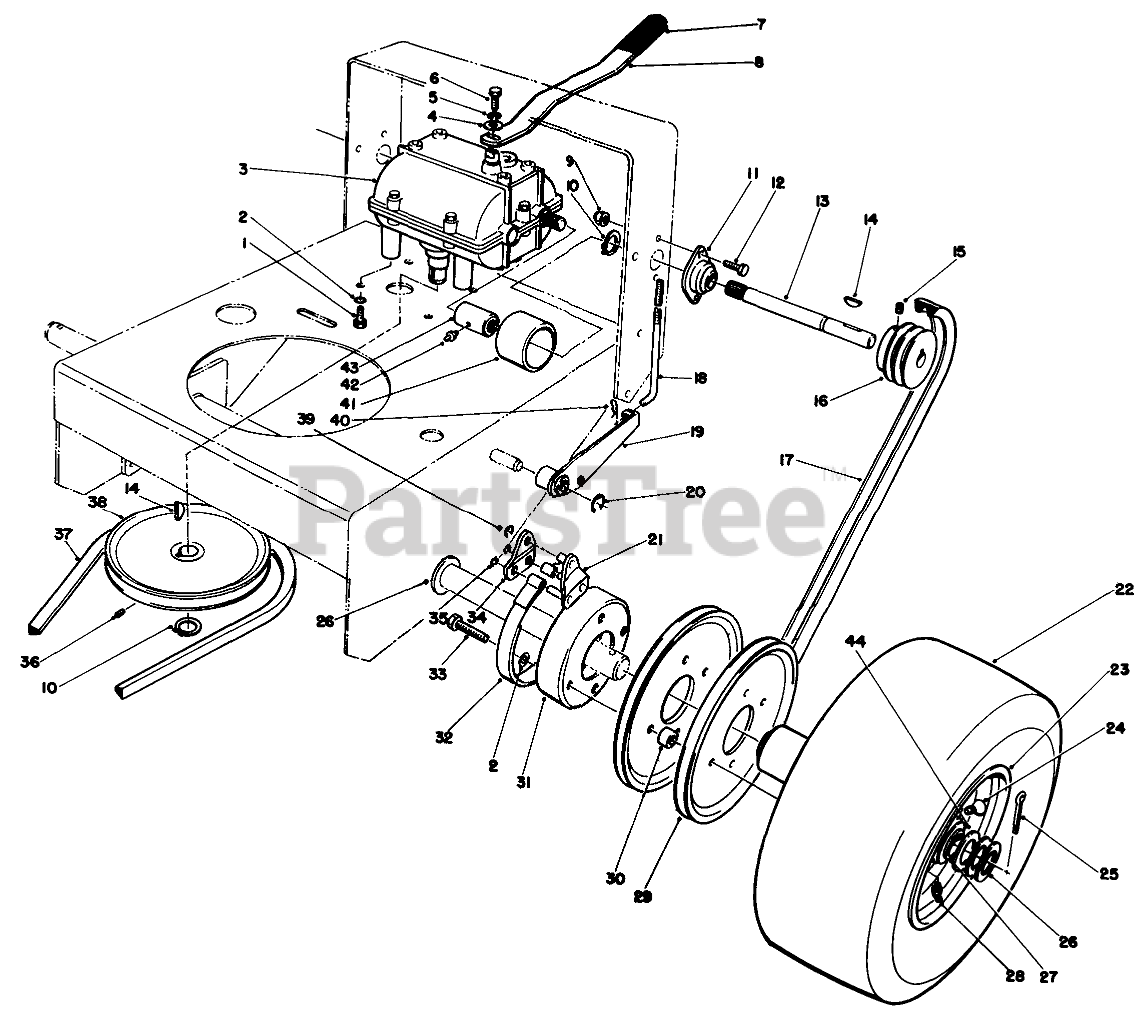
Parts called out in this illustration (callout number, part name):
1	SCREW-HH
2	WASHER-LOCK
3	Transmission
4	SPACER
5	WASHER-LOCK
6	SCREW-HH
8	LEVER-SHIFT
9	NUT-LOCK, NI
10	RING-SNAP, EXTERNAL
11	BEARING-EXTERNAL SHAFT
12	SCREW-HH
14	KEY-WOODRUFF
15	SCREW-SET, HSH
16	Pulley-Drive
17	V-BELT
18	ROD-BRAKE
19	Brake Arm-LH
20	RING-RETAINING
21	LINK-BRAKE
23	WHEEL AND HUB ASM
24	STEM-VALVE
25	PIN-COTTER
26	WASHER-WHEEL
27	BEARING-BALL, FLANGED
28	FITTING-LUBE, 45 DEG
29	Pulley-Wheel
30	SPACER-PULLEY
31	Drum-Brake
32	BAND-BRAKE
33	SCREW-HH
34	Plate-Link
35	RING-RETAINING
36	SCREW-SET
37	V-BELT
38	PULLEY-DRIVEN
39	RING-RETAINING, EXTERNAL
40	PIN-COTTER
41	GUARD-COUPLER
42	FITTING-GREASE
43	COUPLER
44	WASHER-THRUST
